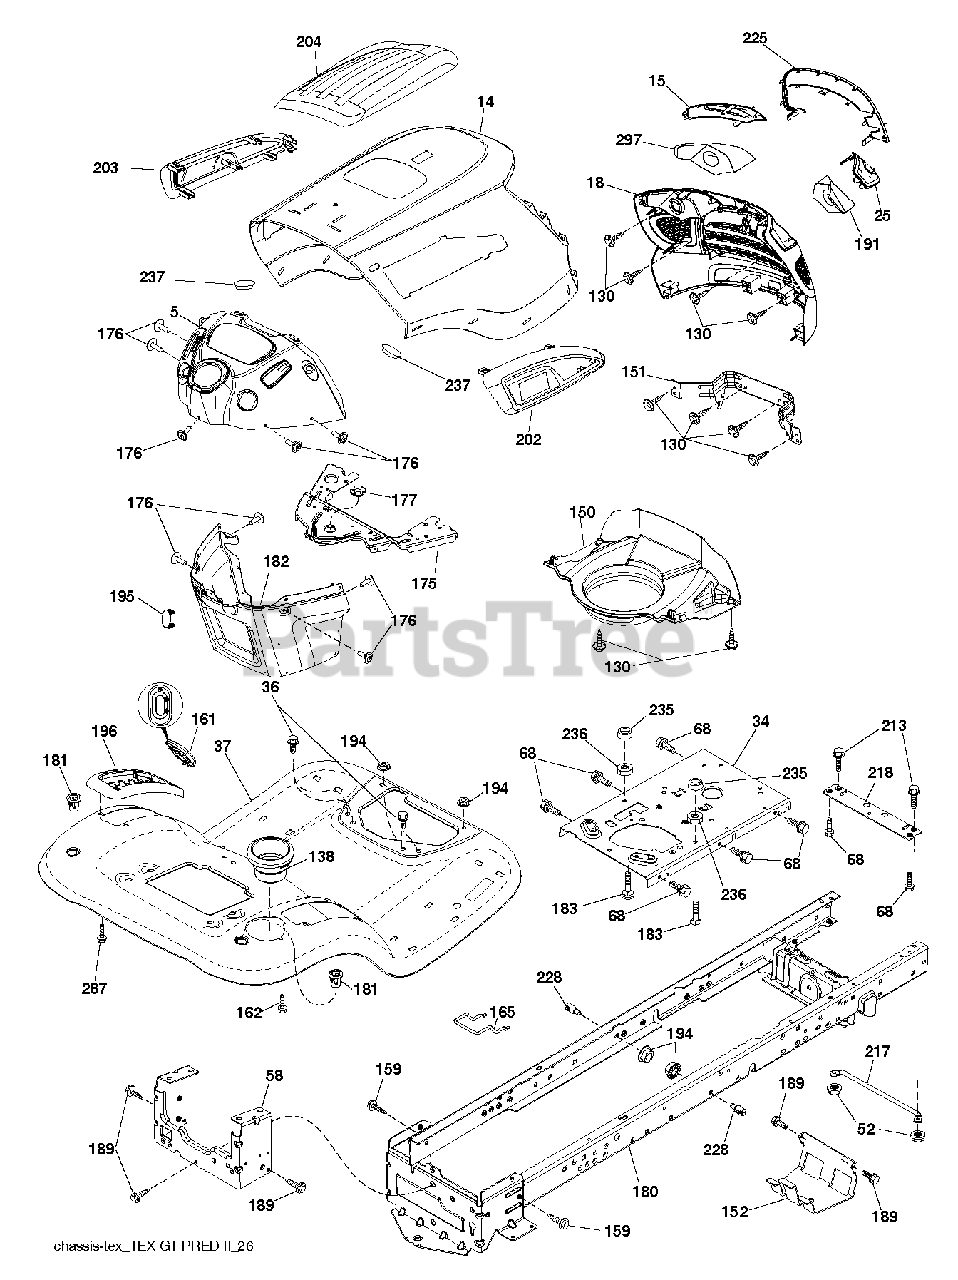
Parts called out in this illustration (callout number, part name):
5	DASH.UPPER.PREDATOR.M/C.BLACK
14	HOOD.PREDATOR.YT/GT.PNT428
15	LENS.MCCULLOCH.GT.LH
18	GRILLE.PREDGT2.GEN
25	Lens, RH Mcculloch GT
34	PLATE.ENGINE.WELDED.CHASSIS
36	SCREW 5/16"
37	FENDER.TLT.W/CPH.W/FW.BLACK
52	LOCKNUT
58	DRAWBAR UPPER 2PC SMALL FENDER
68	SCREW LT
130	SCREW.#10 X 0.750.BOS (2 2)
138	CUPHOLDER.TL.TEX.BLACK
150	AIR DUCT.HOOD.PRED YT/GT(2 2)
151	BRACKET.PIVOT.PREDATOR
152	SHIELD.BROWNING.W/TEX
159	SCREW, 3/8-16X3/4
161	WINDOW.FUEL.LT.TEX.BLACK
162	SCREW.HI-LO.CONSOLE
165	SUPPORT.TANK.REAR.W/TEX
175	PLATE.CROSSMEMBER.HUSQ
176	SCREW.#10-24X5/8.RN.QU
177	BUSHING STEERING
180	CHASS.WLDMNT.TL.12GA/2P.48/54
181	FEND/FTRST.PCH.CPH.NFW
182	DASH LOWER.HUSQ.PRED NO CRUISE
183	BOLT.5/16-18X1-1/4 FULL THD
189	SCREW
191	REFLECTOR.MCCULLOCH.GT.RH
194	NUT LOCK HEX FLANGE 5/16-18
195	PLUG.HOLE.DASH.
202	VENT.SIDE.HOOD.RH.PREDATOR
203	VENT.SIDE.HOOD.LH.PREDATOR
204	VENT ASM.TOP.PRED GT PRO.428
213	BOLT
217	ROD.PIVOT.HOOD
218	X-PIECE.HOOD.STOP.NON/
228	STUD.FASTNER.W/ANTI-ROTATE
235	SPACER FENDER
236	NUT.CENTERLOCK.5/16-
237	PLUG.MOUNT.CARGO.BLK
287	SCREW 1/4X20
297	REFLECTOR.MCCULLOCH.GT.LH
